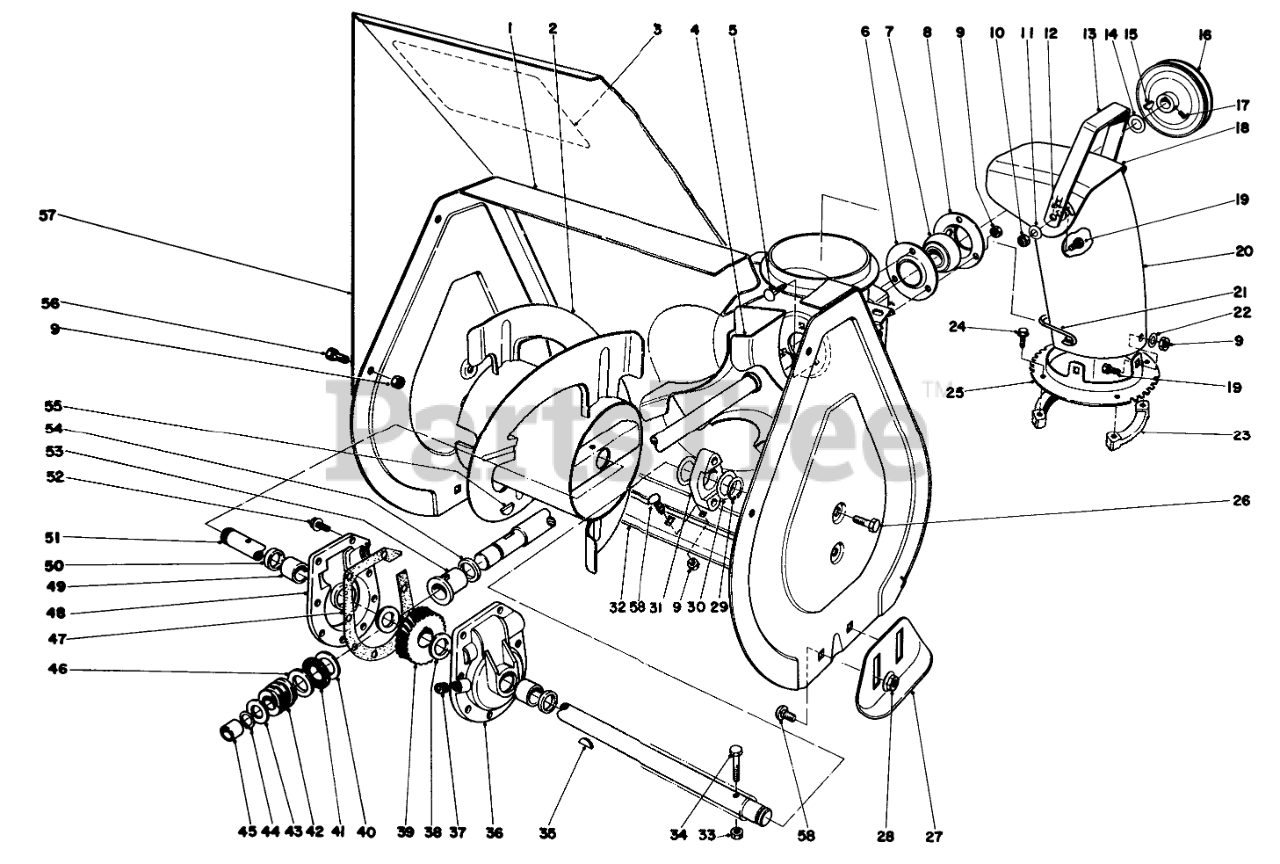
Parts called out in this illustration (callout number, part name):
1	Auger Housing
2	Auger R.H.
3	Decal
4	Shaft & Impeiler
5	BOLT-CARR
6	FLANGE-CUP, BEARING
7	Ball Bearing
8	FLANGE-CUP, BEARING
9	NUT-LOCK, NI
10	NUT-LOCK, CONE
11	WASHER-BELLEVILLE
12	Rubber Washer
13	Handle Deflector
14	WASHER
15	KEY-WOODRUFF
16	PULLEY
17	Set Screw
18	Deflector
19	SCREW-HH
20	Chute-Discharge
21	Chute Guard
22	WASHER-PLAIN
23	RING-CHUTE, RETAINER
24	SCREW-SPECIAL
25	Chute Ring
26	SCREW-HWHTF
27	Skid
28	NUT-HF
29	RING-RETAINING
30	WASHER
31	BEARING-AUGER
32	Blade-Scraper
33	NUT-LOCK, CONE
34	SCREW-HH
35	KEY-WOODRUFF
36	Gear Case L.H. (Incl. Ref. #49 & 50)
37	PLUG-PIPE, SQH
38	WASHER-THRUST
39	Gear
40	WASHER-THRUST
41	BEARING-THRUST
43	WASHER-THRUST
44	Ring-Snap
45	BUSHING
46	WASHER-THRUST
47	asket
48	Gear Case R.H. (Incl. Ref. #49 & 50)
49	BUSHING
50	SEAL-OIL
51	AUGER SHAFT
52	SCREW-TAPTITE
53	BUSHING-INPUT
54	RING-QUAD
55	KEY-WOODRUFF
56	SCREW-HH
57	AUGER EXT 21 SCAND
58	BOLT-CARR
